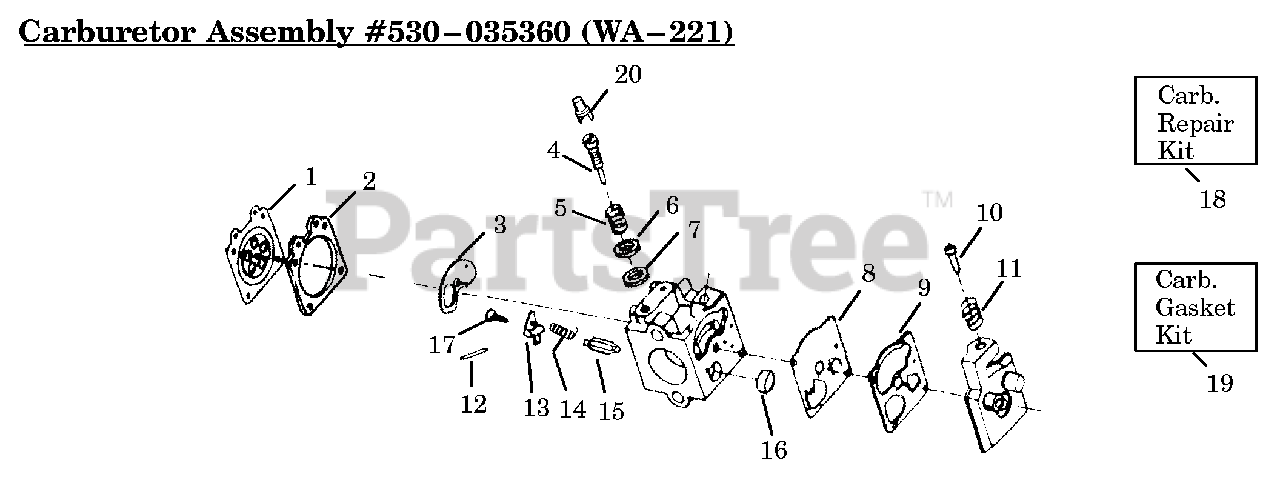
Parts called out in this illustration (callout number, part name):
1	Metering Diaphragm
2	Metering Diaphragm Gasket
3	Circuit Plate Gasket
4	Mixture Needle
5	Mixture Needle Spring
6	Mixture Needle Washer
7	"O" Ring Mixture
8	Fuel Pump Diaphragm
9	Fuel Pump Gasket
10	Idle Speed Screw
11	Idle Speed Spring
12	Metering Lever Pin
13	Metering Lever
14	Metering Lever Spring
15	Inlet Needle Valve
16	Fuel Inlet Screen
17	Metering Lever Pin Screw
18	Carb. Kwik Repair Kit
19	Carb. Gasket/Diaphragm
20	Limiter Cap
530-035360	Carburetor Assembly - WA-221
